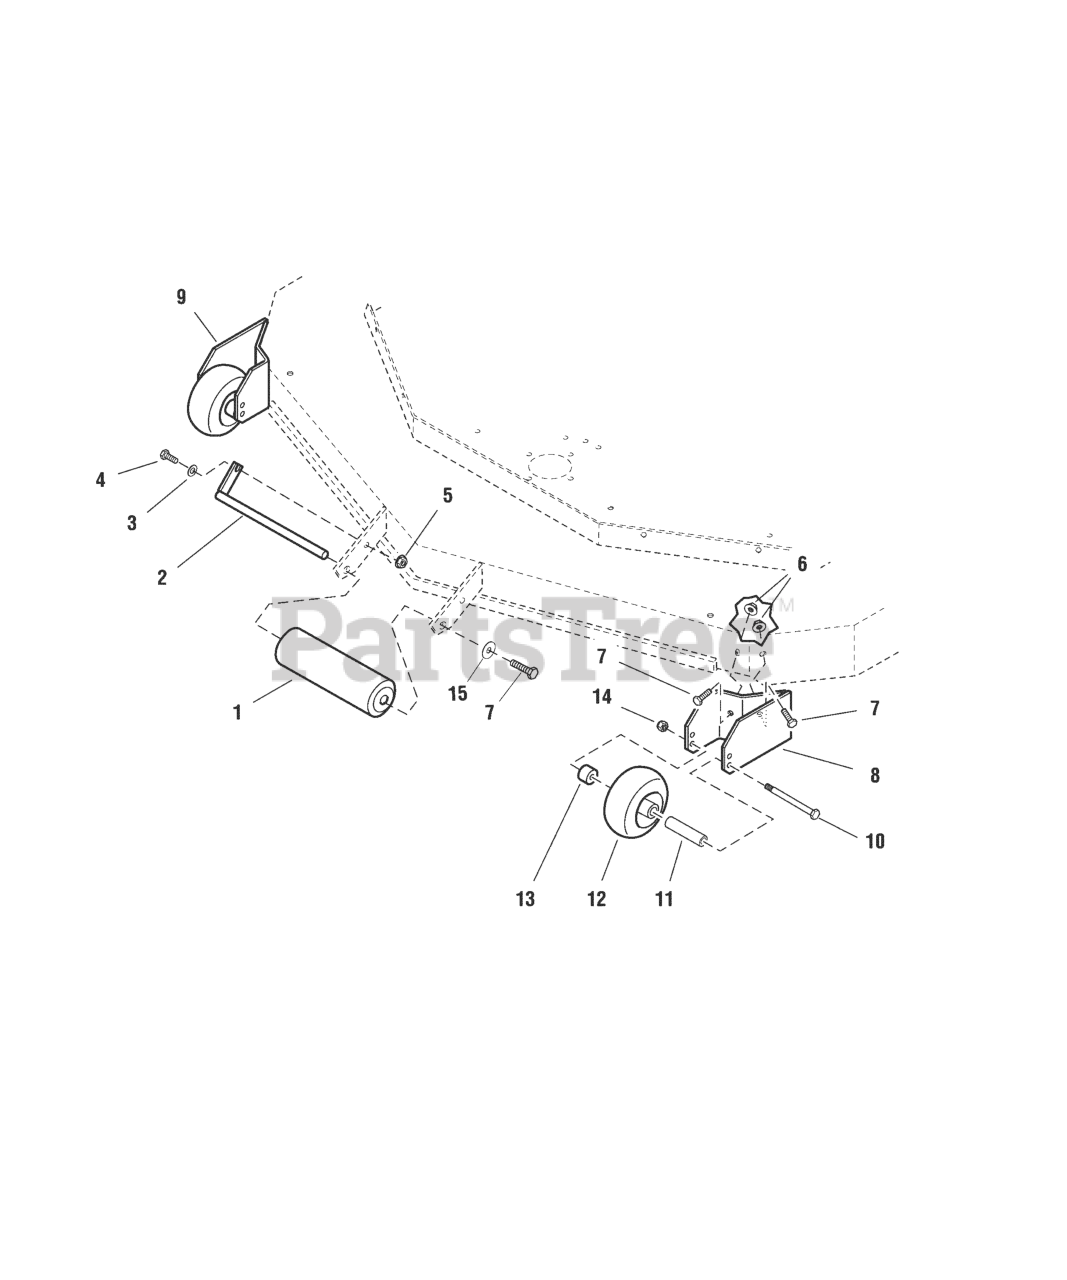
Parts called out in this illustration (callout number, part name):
1	ROLLER
3	WASHER, 5/16" SAE
4	BOLT, 5/16-18 X 1 GD5 YZ
5	NUT, 5/16-18 HEX SERRATED FLANGE (LARGE)
6	NUT, 3/8-16 Hex Serrated Flange
7	BOLT, 3/8-16 X 1" GD5 CZ
8	CASTER MOUNT-LH
9	CASTER MOUNT-RH
10	BOLT, 3/8-16 X 4-1/2" GD5 CZ
11	SPACER, .39 x .63 x 2.56
12	GAUGE WHEEL
13	SPACER, .39 x 1.00 x .79
14	NUT, 3/8-16 HEX NYLON LOCK
15	WASHER, .390 X 1.50 X .109 YZ
